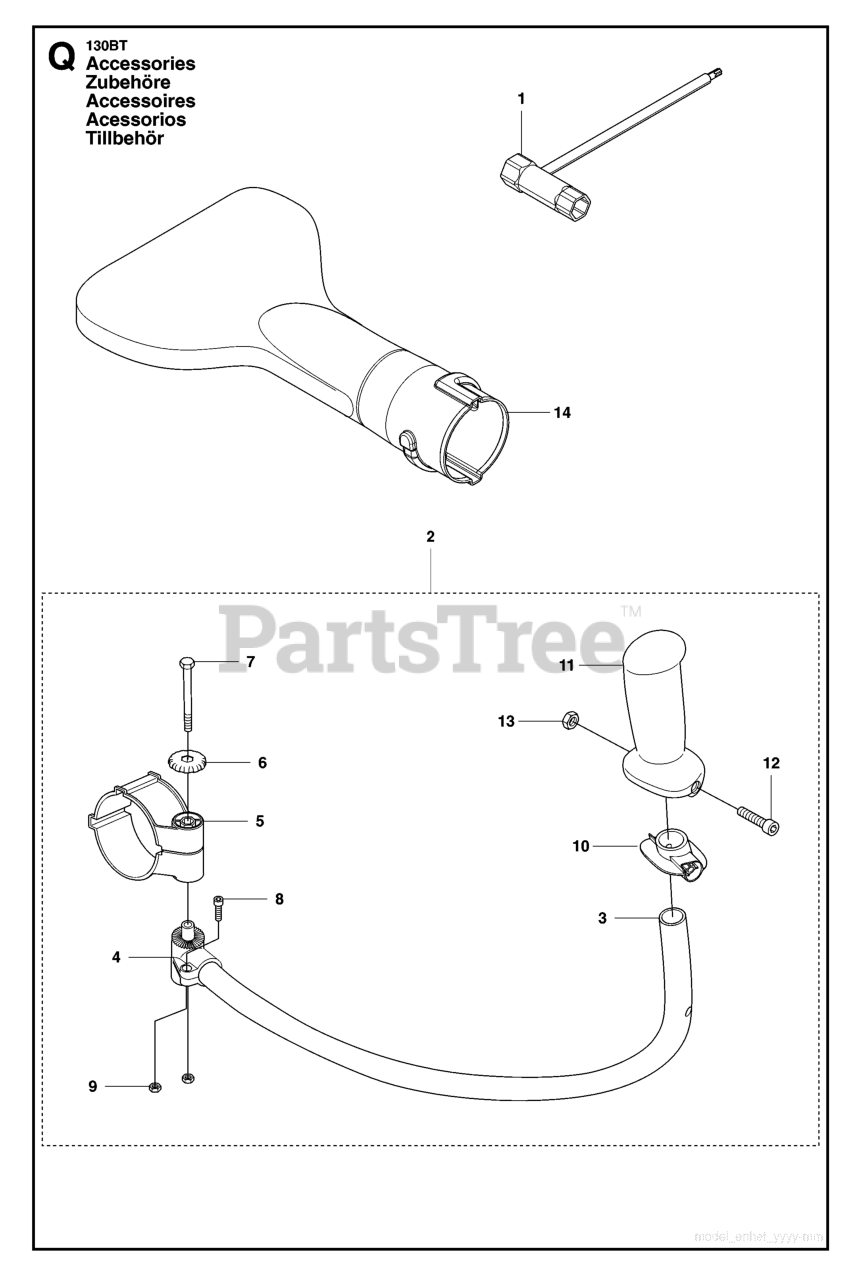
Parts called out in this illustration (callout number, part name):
1	SOCKET
2	HANDLEBAR ASSY
8	SCREW MC6S 5X10
14	FLAT NOZZLE
